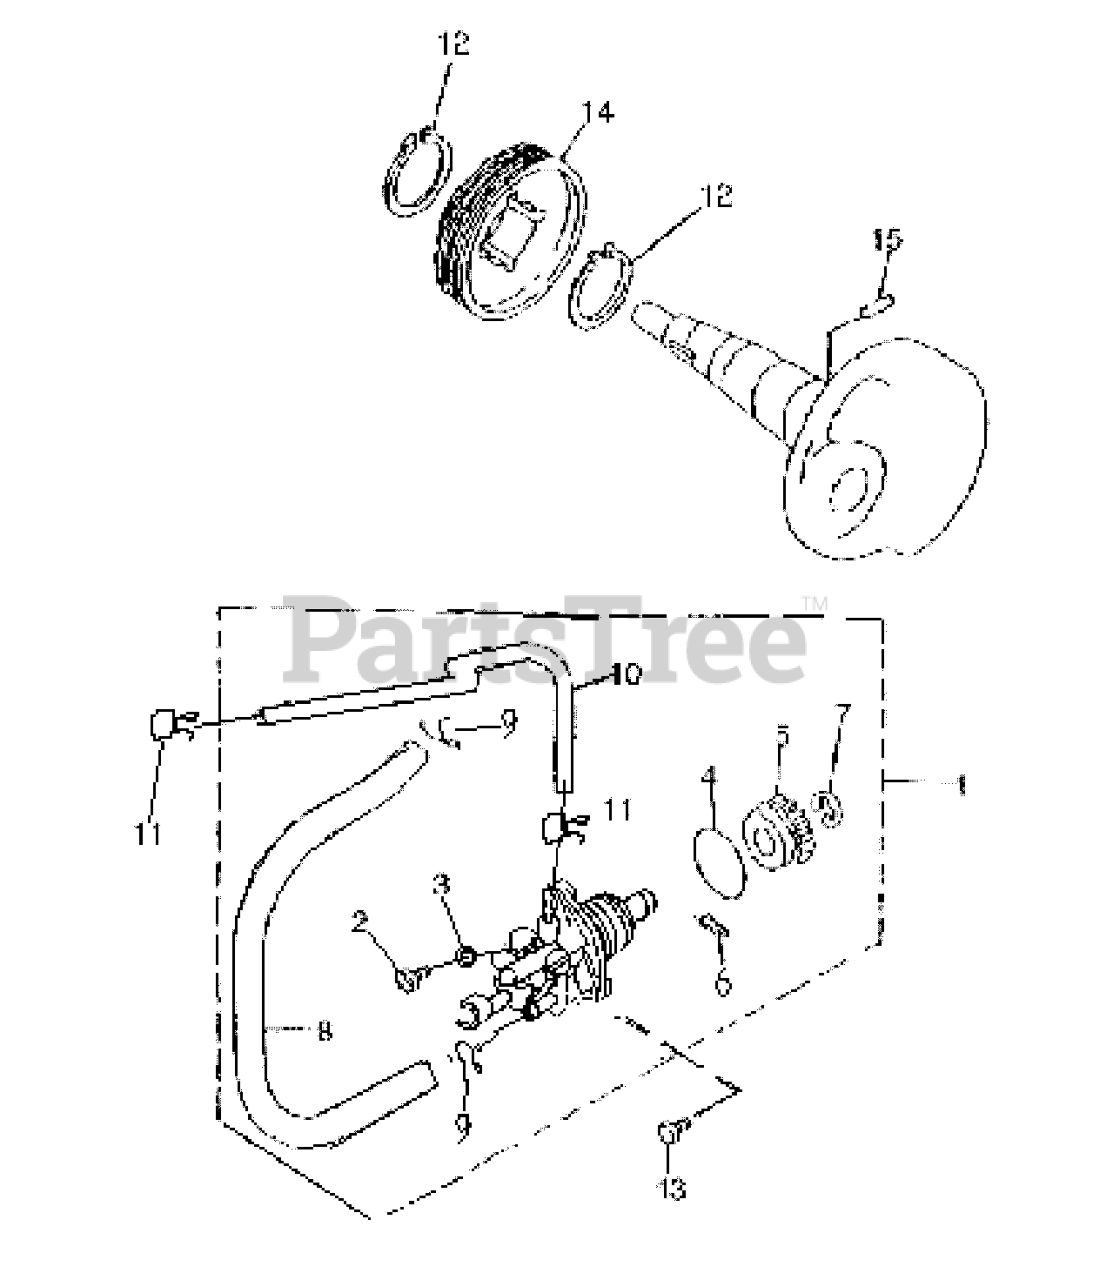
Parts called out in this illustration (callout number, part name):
1	OIL PUMP ASSY
2	SCREW
3	WASHER
4	O-RING
5	GEAR
6	PIN
7	CIRCLIP
8	HOSE
9	HOSE CLIP
10	HOSE
11	HOSE CLIP (I
12	CIRCLIP
14	PUMP DRIVE GEAR
